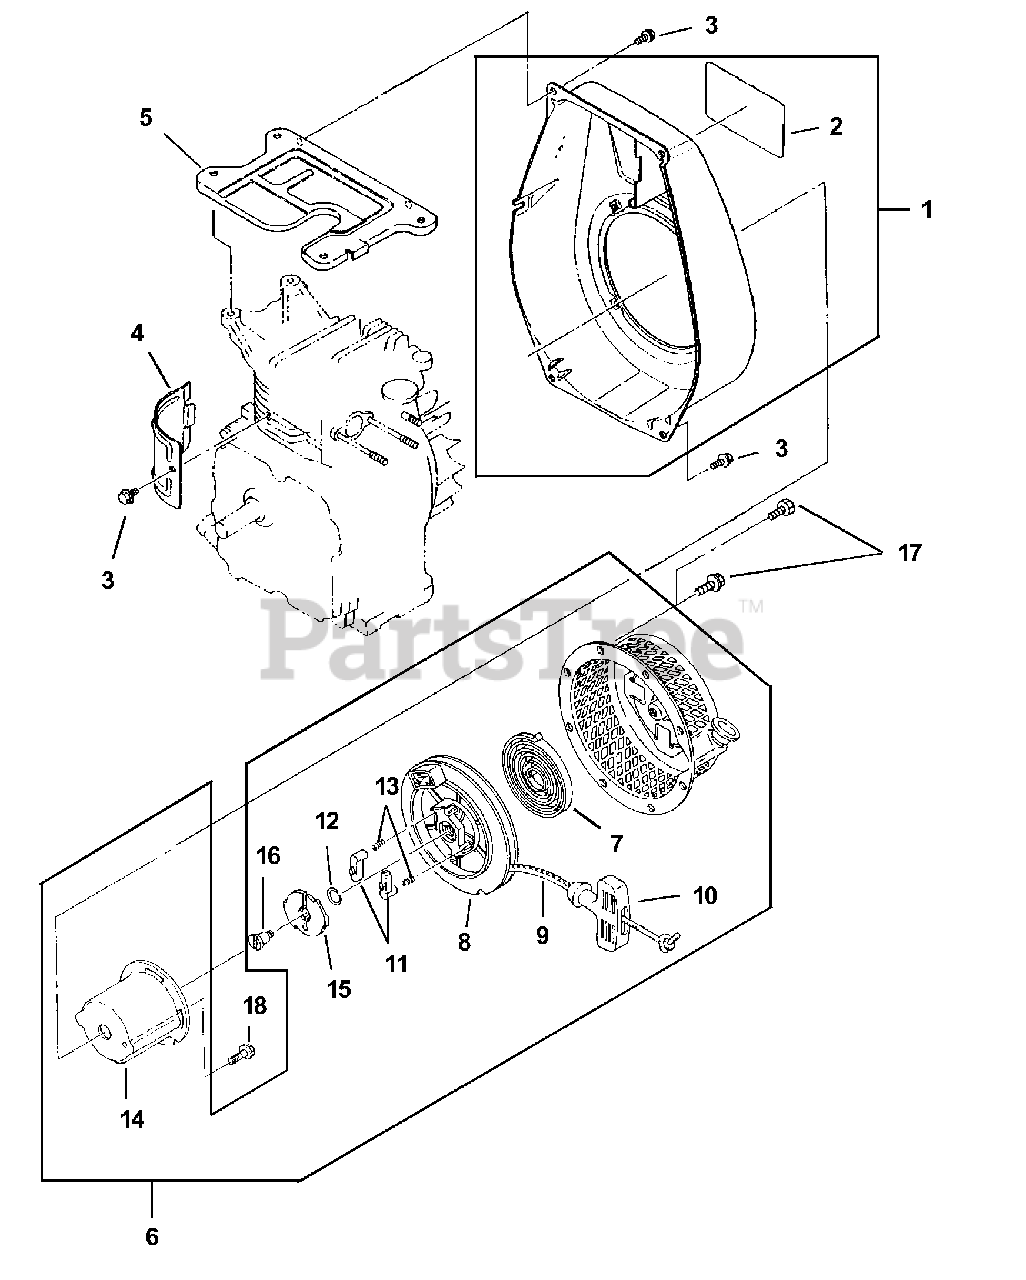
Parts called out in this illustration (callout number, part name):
1	Blower housing
2	Label (trademark)
3	Flange bolt (M6 X 1.0 X 12L)
4	Cylinder baffle
5	Head cover
6	Starter assy
7	Spring rewind
9	Starter rope
10	Starter knob
12	Friction spring
13	Return spring
14	Starter cup
15	Ratchet guide
16	Set screw (M6 X 1.0 X 14L)
17	Flange bolt (M6 X 1.0 X 8L)
18	Flange bolt (M6 X 1.0 X 14L)
